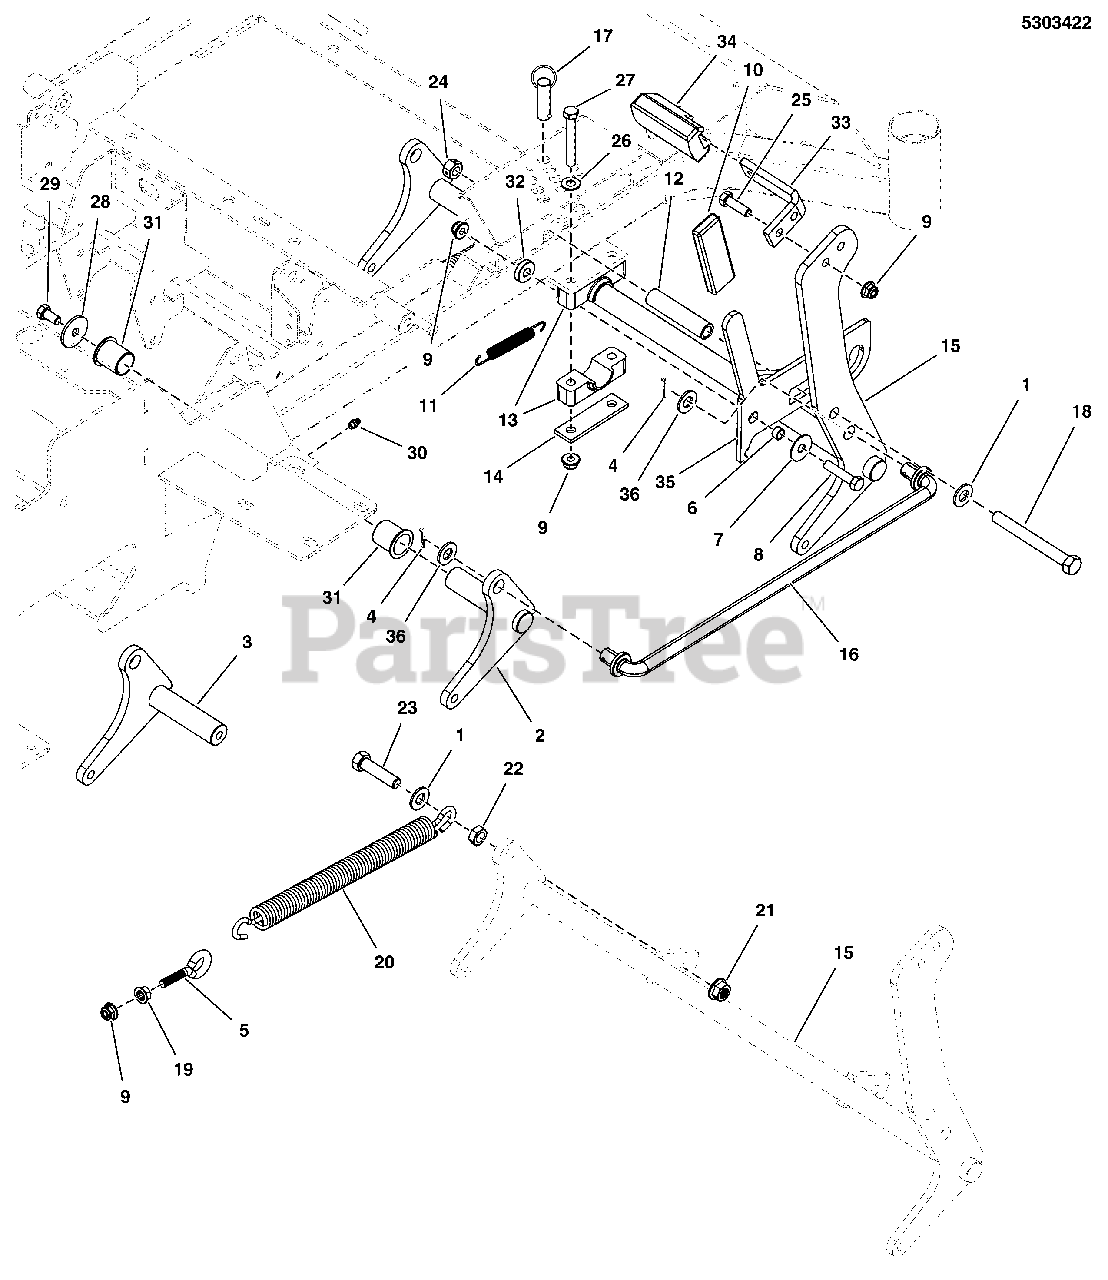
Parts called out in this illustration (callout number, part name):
1	WASHER, 1/2" SAE
2	WELD, DECK LIFT PIVOT, RH
3	WELD, DECK LIFT PIVOT, LH
4	PIN, COTTER, 1/8 X 1-1/4
5	EYEBOLT, 3/8-16 X 4, 2.13THRD, .75EYE, C
6	SPACER, .38 X .50 X .27, CZ
7	WASHER, 3/8 FENDER
8	BOLT, 3/8-16 X 1-3/4 GD5
9	NUT, Hex Flange, Nylock, 3/8-16
10	GRIP, FOAM, 1/4 X 1
11	SPRING, EXTENTION, .50 OD X 4.12 FL
12	SPACER, .53 X .73 X 3.38, CZ
13	PIVOT BLOCK, PLASTIC
14	PLATE, Pivot
15	WELD, DECK LIFT SHAFT - RED
16	ROD, DECK LIFT, S550
17	PIN, COTTERLESS
18	BOLT, 1/2-13 X 4-1/2 GD5 YZ
19	NUT, 3/8-16 HEX SERRATED FLANGE
20	SPRING-EXT, 1.00 ODX13.25LGX.177WR, BLK
21	NUT, 1/2-13 HEX NYLOCK FLANGE
22	NUT, 1/2-13 HEX JAM
23	BOLT, 1/2-13 X 2 GD5 YZ
24	NUT, 1/2-13 HEX SIDE LOCK
25	BOLT, 3/8-16 X 1-1/4 GD5
26	WASHER, 3/8 SAE
27	BOLT, 3/8-16 X 2-3/4 GD5 YZ
28	WASHER, .390 X 1.50 X .109, YZ
29	BOLT, 3/8-16 X 3/4, PLT W/PATCH
30	GREASE FITTING, 1/4-28 STRAIGHT
31	BUSHING, 1.00 X 1.13 X 1.38, PLASTIC
32	SPACER, .39 X 1.00 X .25
33	PEDAL, FOOT - BLK
34	PEDAL, Rubber
35	PLATE, DECK TRANSPORT LEVER - BLK
36	WASHER, 5/8 SAE
